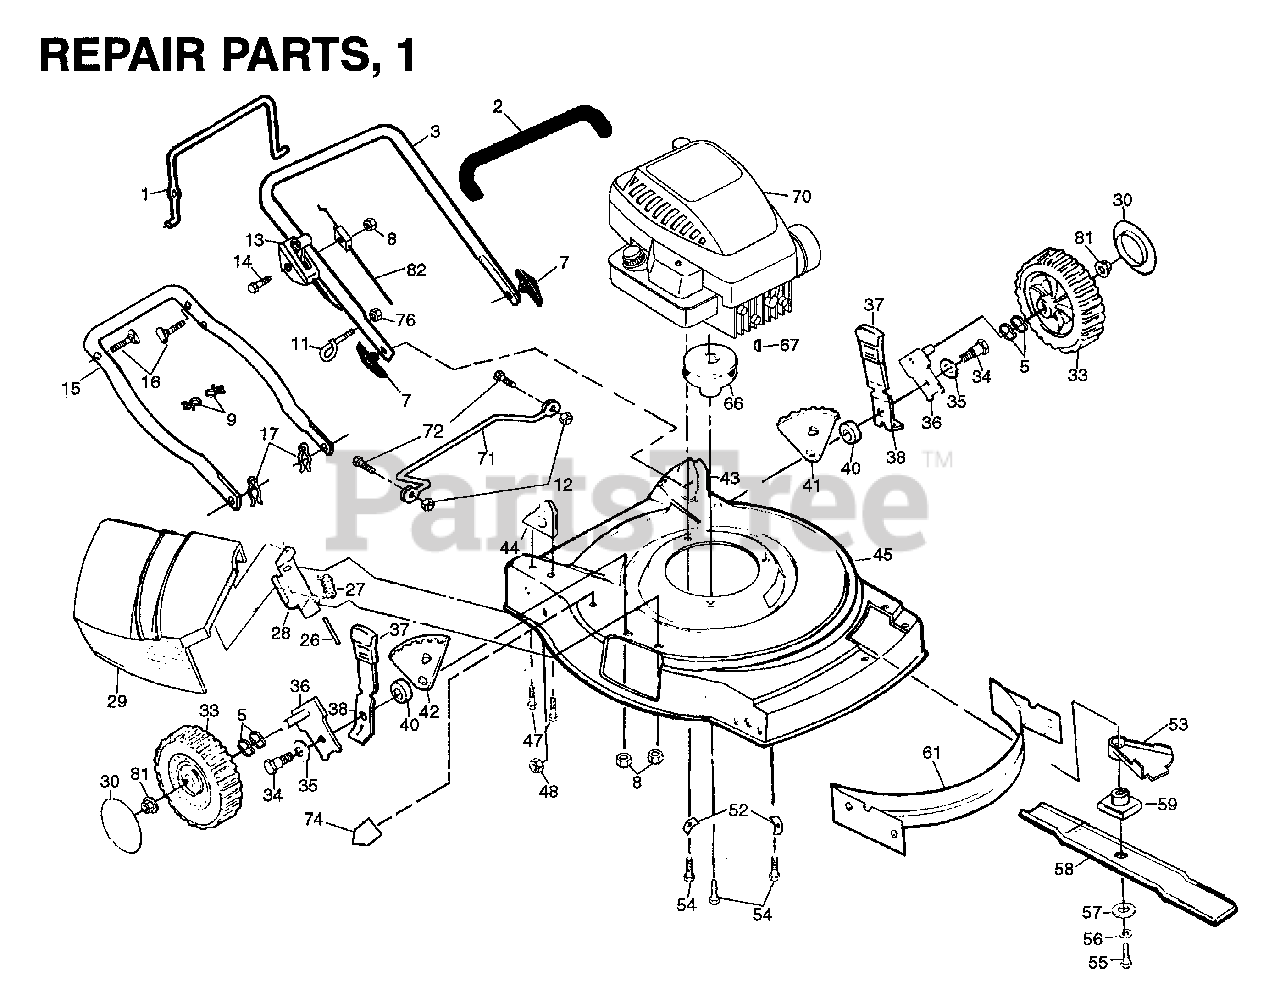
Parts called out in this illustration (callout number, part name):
1	BAIL.CNTRL.SRD.CM
2	HANDLE GRIP
5	WAVE WASHER
7	HANDLE KNOB
8	NUT.CROWNLOCK.1/4
9	CLIP CABLE SNAP
11	ROPE GUIDE
13	THROTTLE CONTROL
14	SCREW 1/4-20 X 2.12
16	HANDLE BOLT
17	HAIRPIN COTTER
26	ROD.HINGE.COMBI-C
27	SPRING PM
28	BRACKET PM
33	WHEEL.8X2.PR.LP.RAD.GREY
34	BOLT
35	BELLEVILLE WASHER
36	AXLE ARM
37	SELECTOR KNOB
40	RP SPACER HT ADJ
43	HDLE BRKT ASSY LH
44	HDLE BRKT ASSY RH
47	SCREW
48	LOCKNUT
49	NUT.CROWNLOCK.1/4
53	COVER
54	BOLT
55	SCREW, HEX HD 3/8-24 X 1-3/8
56	LOCKWASHER
57	WASHER,HARDEN
58	BLADE 22"
59	RP BLADE ADAPTOR
66	ENGINE.PULLEY.FWG
67	HI PRO KEY PM
74	DECAL MOWER CUT/FINGER
76	NUT.CROWNLOCK.1/4
81	HEX FLANGE LOCKNT
